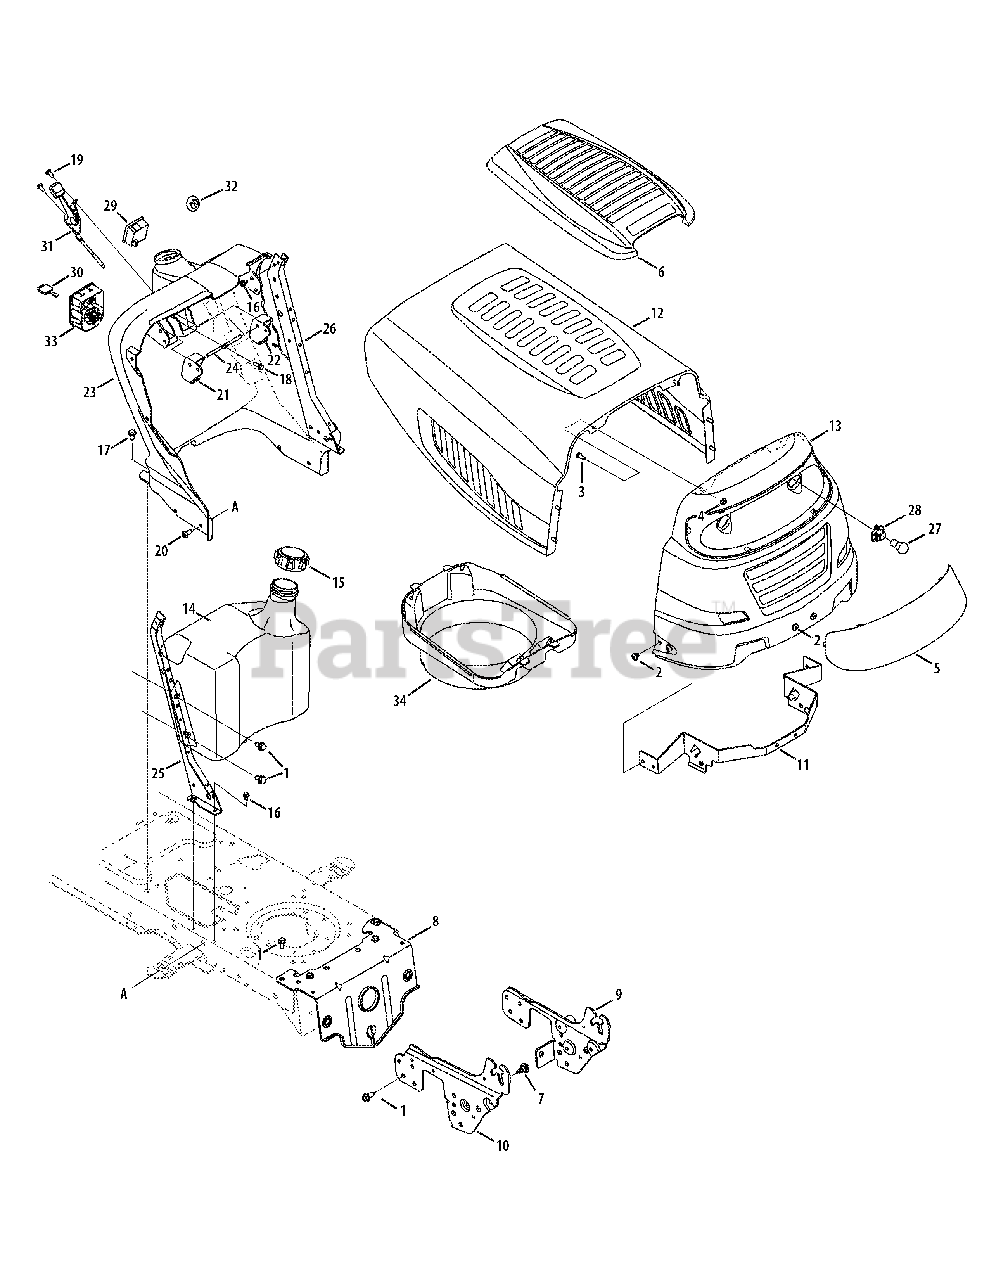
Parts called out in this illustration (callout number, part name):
1	Screw, 5/16-18, 0.625
2	Screw, 5/16-18, .375
3	Screw, 1/4-20, 0.620
4	Flange Lock Nut, 1/4-20
5	1/5-Style Lens
6	Hood Cover/Scoop
7	Screw, Shldr, .43 x .29, 5/16-18
8	Pivot Bar Bracket
9	Pivot Bracket Support LH
10	Pivot Bracket Support RH
11	Hood Pivot Bracket
12	1/5-Style Hood
13	1/5-Style Grill
14	Fuel Tank, 2.0 gal.
15	Fuel Tank Cap
16	Screw, 1/4-20, 0.500
17	Screw, 5/16-18 x 0.500
18	Screw, 1/4-15, .750
19	Screw, 1/4-14, 0.625
20	Screw, 5/16-18, 0.750
21	Dash Cruise Lever
22	Dash Brake Lever
23	Dash Panel, w/ Manual PTO
24	Bent Lever Rod
25	Dash Support, RH
26	Dash Support, LH
27	Headlamp, 12V
28	Lamp Socket
29	Systems Ind. Monitor w/ Amtr.
30	Key w/ Plastic Grip
31	Throttle/Choke Control, 25.0
32	Choke Plug
33	3-Position Key Switch
34	Hood Plenum
